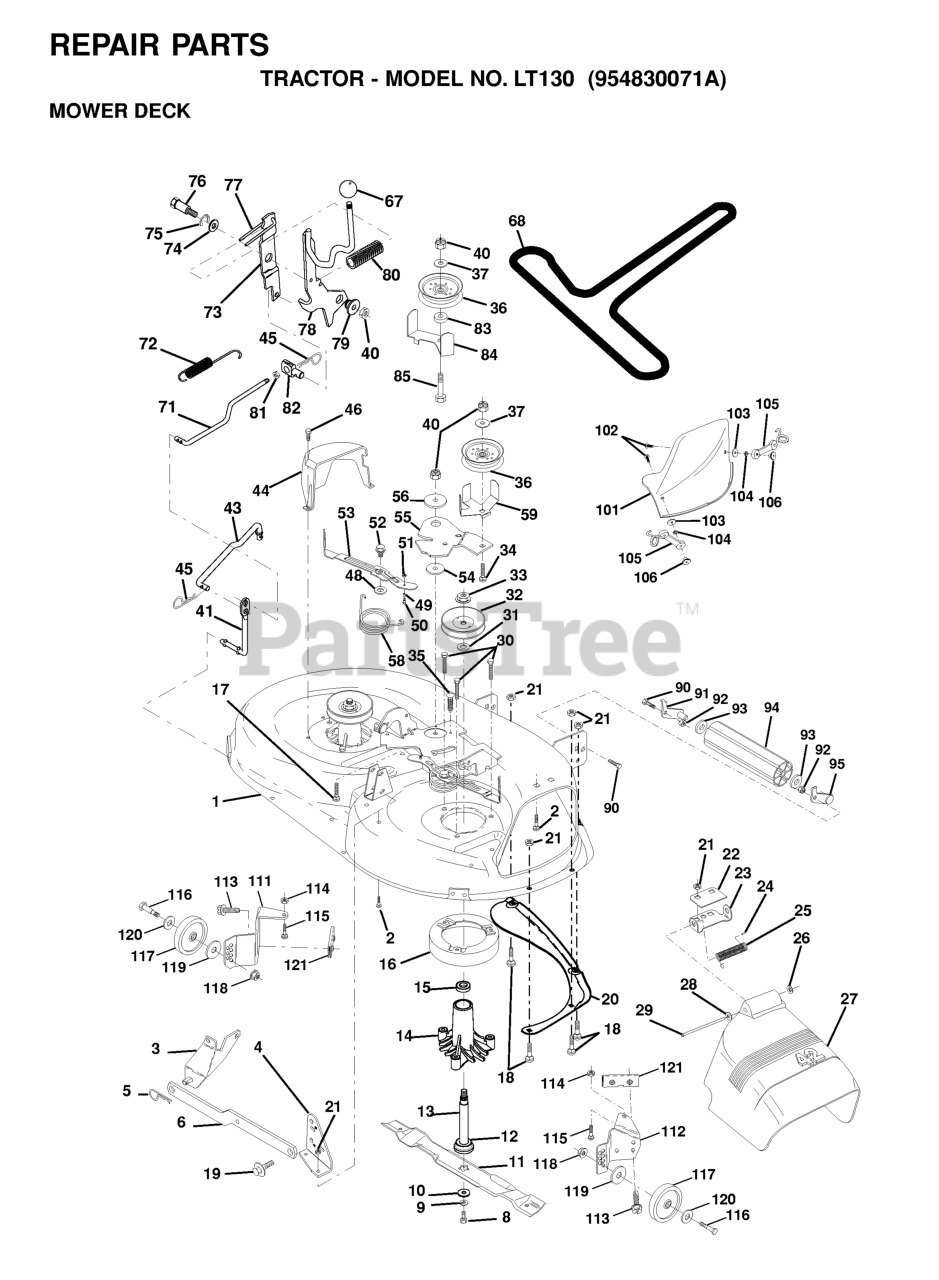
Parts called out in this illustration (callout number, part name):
1	DECK 42"
2	RP BOLT 5/16-18 X3/4 ZN/YEL GR
3	BRKT ASM SWAY BAR
4	BRKT DECK SW BAR
5	RETAINER-SPRNG RB
6	REAR SUSP ARM
8	BLADE BOLT
9	LOCKWASHER
10	WASHER.BLADE
11	BLADE.42".MULCH
12	BEARING.BALL.#6204.(MANDREL)
13	SHAFT ASM VENT
14	HOUSING.MANDREL.VENTED (MACHD)
16	STRIPPER
17	BOLT
18	BOLT
19	BOLT SHD 5/16-18
20	BAFFLE
21	LOCKNUT
22	STIFFENER BRACKET
23	DEFLECTOR BRACKET
24	CAP-SLEEVE LT
25	SPRING TORSION
26	NUT PUSH M
27	SHIELD.DEFLECTOR.MOWER.42".BLK
28	Washer 11/32 x 5/8 x 16 Ga SD
29	ROD.HINGE
30	SCREW
31	WASHER
32	MANDREL PULLEY
33	NUT
35	FASTENER.XMAS.TREE
36	FLAT IDLER PULLEY
37	WASHER
43	CLUTCH ROD
44	GUARD MANDREL LH BLACK
45	RETAINER M
46	SCREW.1/4-20X5/8
49	CAM FOLLOWER
52	BOLT.SHOULDER.5/16-18
53	ARM
54	HARDENED WASHER
55	IDLER ARM
56	SPACER RETAINER
59	GUARD, BELT
67	KNOB T (1/2-HOLE)
68	V-BELT TRIPATH
71	CLUTCH ROD
72	RETURN SPRING
73	ARM CLUTCH SECONDARY
77	KEEPER SPRING
78	CLUTCH ARM
79	BUSHING.FLANGE.E-RING.GROOVE
80	SPRING
81	NUT
82	TRUNNION.ADJUSTABLE.3/8-16
84	KEEPER BELT
85	BOLT
90	BOLT
91	BRACKET LH (A)
92	NUT
93	Washer 1 17/32 X 7/8 X 16 Ga
94	NOSE ROLLER
95	BRACKET RH (B)
101	COVER MULCH 42"
102	SCREW
104	LOCKWASHER #10
105	LATCH ASSEMBLY
106	WELDNUT
111	BRACKET
112	BRACKET
113	SCREW.THDROL.5/16-18X3/4.TTY
114	NUT
115	BOLT.CARR.5/16-18X1/2
116	BOLT M
117	WHEEL.GAUGE.BLK.4.93
118	LOCKNUT
119	WASHER.5/16.FLAT.STE.STD.
120	Washer 17/32 x 15/16 x 12 Gauge
121	BRACKET.EXTRUDED.GAGE.WHEEL
